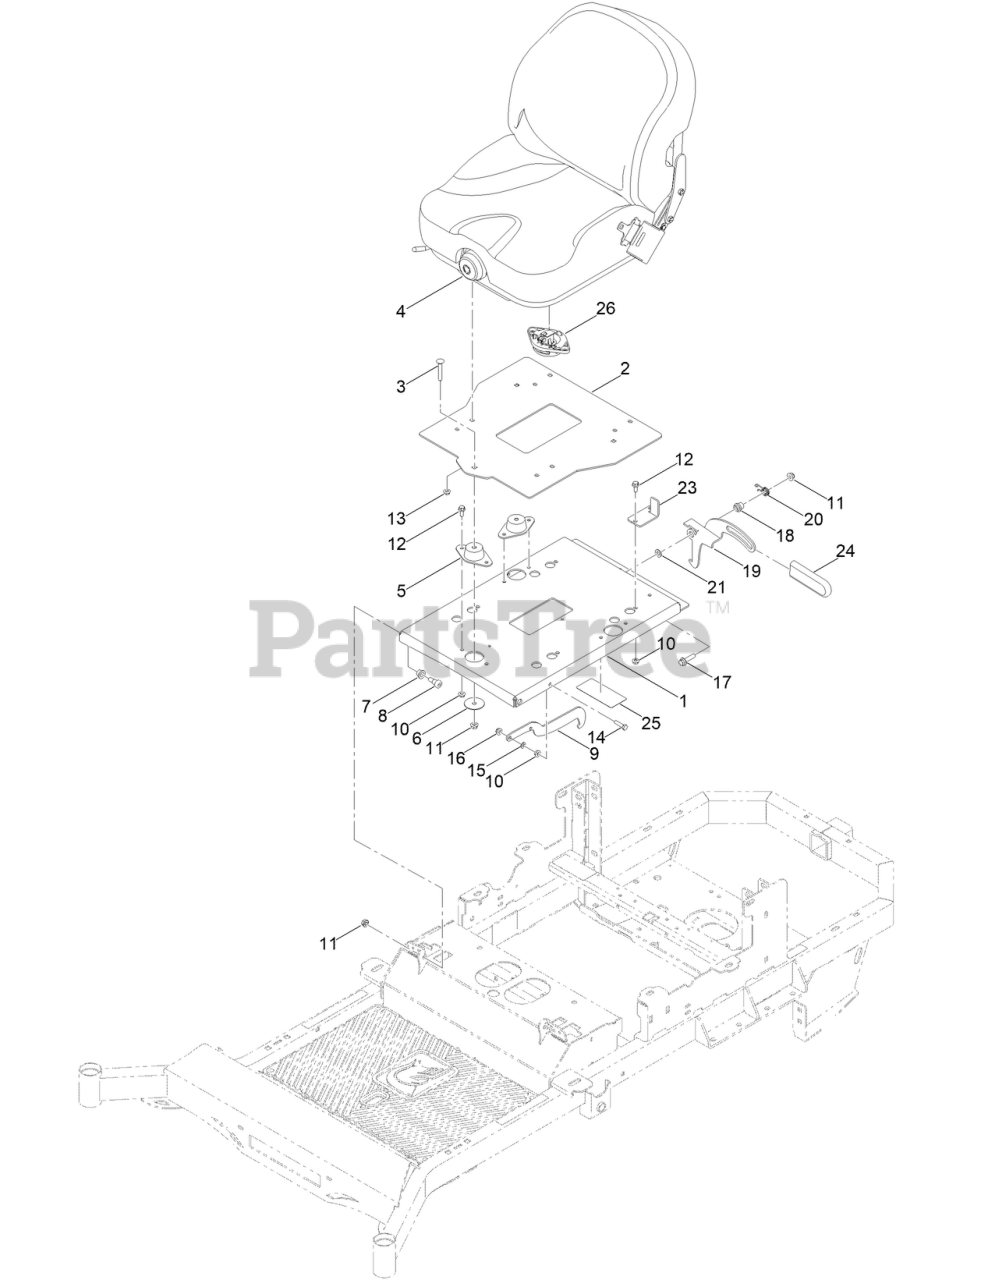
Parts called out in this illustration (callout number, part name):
1	360 SEAT BASE PLATE SAFTY DECAL ASM-P11
2	2019 UPGRADE SEAT PLATE PAINT
3	SCREW-CARR
4	2019 FULL SUSP SEAT
5	FLOATING SEAT DAMPER-STIFFER
6	3/8 X 2IN OD FENDER WASHER YZ
7	1/2IN ID X 5/8IN OD X 1/2IN FLANGE BUSH
8	1/2 X 1/2 SOCKET SHOULDER BOLT ZC YELLOW
9	MWR SEAT LATCH HOOK PAINT
12	SCREW-HHF
13	5/16-18 NYLON INSERT FLANGE L/NUT ZC
14	SCREW-HH
15	.312IDX.625ODX.062 THK THRUST BRG OI BRZ
16	NUT-HF, NI
17	SCREW-HHF
18	BUSHING-LATCH, SEAT
19	BRACKET-LATCH
20	SPRING-TORSION, LATCH
21	WASHER-FLAT
23	BKT-STOP, SLIDE
24	STAND UP MWR BRAKE ARM GRIP
25	DECAL-WARNING, BATTERY
26	MWR SEAT SWITCH
